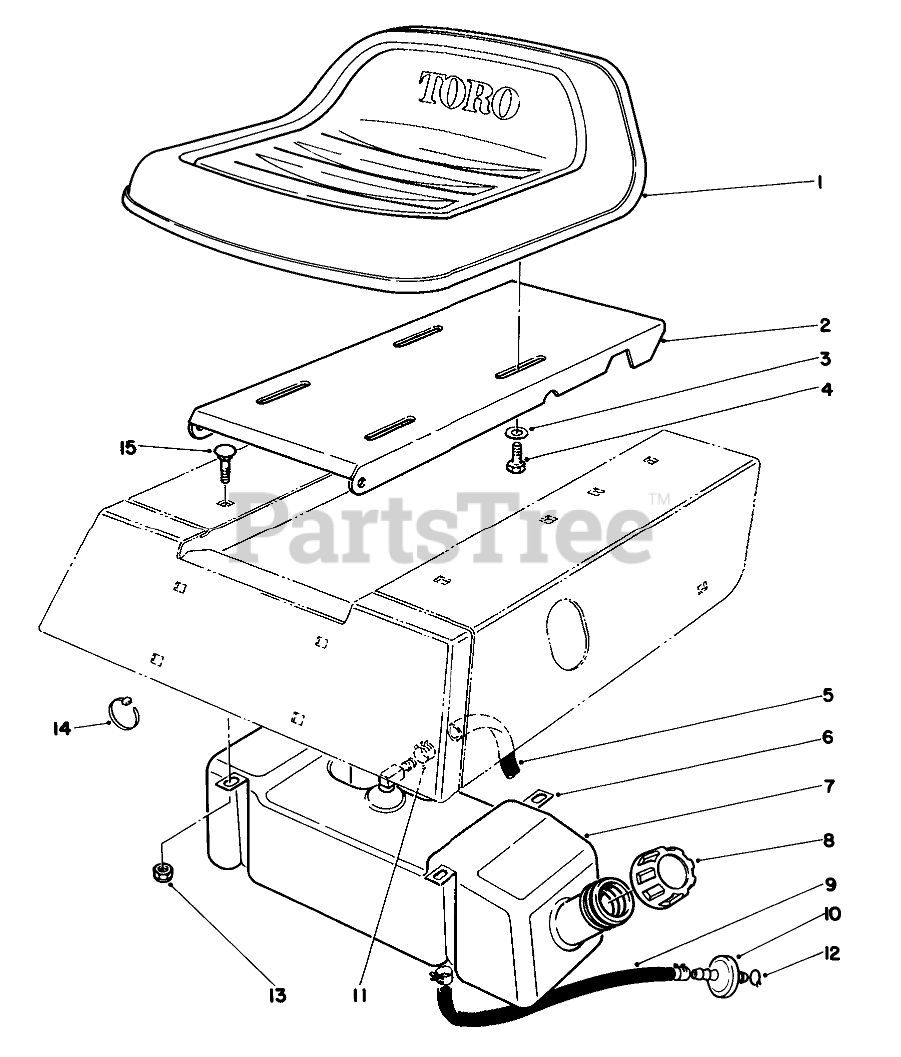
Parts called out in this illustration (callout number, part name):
1	Seat
2	Base-Seat
3	WASHER-FLAT
4	SCREW-HH
5	HOSE-FUEL
6	STRAP-GAS TANK
7	GAS TANK
8	GAS CAP ASSEMBLY
9	HOSE-FUEL
10	FILTER-FUEL
11	FUEL HOSE CLAMP
12	CLAMP-HOSE
13	NUT-LOCK, NI
14	TIE-CABLE
15	SCREW-CARR
